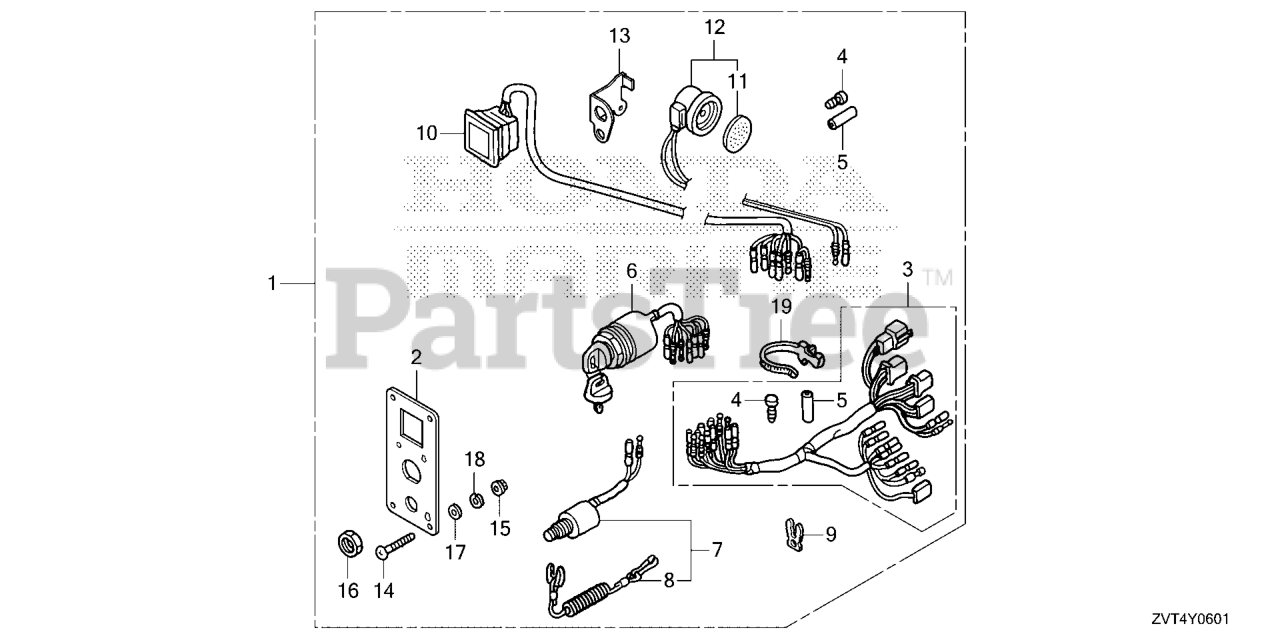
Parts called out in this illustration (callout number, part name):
1	PANEL KIT, SWITCH (4-LED)
2	PANEL, CONTROL
3	HARNESS ASSY., SWITCH PANEL
4	PLUG, CONNECTOR (INNER) (TROLLING CONTROL)
5	PLUG, CONNECTOR (OUTER) (ENGINE NO.)
6	SWITCH ASSY., COMBINATION (SINGLE) (DUAL)
7	SWITCH ASSY., EMERGENCY STOP
8	WIRE, EMERGENCY (SINGLE) (DUAL)
9	CLIP, EMERGENCY LOCK
10	LAMP ASSY., INDICATION (4-LED)
11	PLATE, TURN SIGNAL BUZZER DUAL QTY = (2) (SINGLE)
12	BUZZER, WARNING DUAL QTY = (2) (SINGLE)
13	BRACKET, BUZZER
14	SCREW, PAN (5X40) DUAL QTY = (8) (SINGLE)
15	NUT, FLANGE (5MM)
16	NUT, HEX. (16MM) DUAL QTY = (2) (SINGLE)
17	WASHER, PLAIN (5MM)
18	WASHER, SPG (5MM)
19	BAND, WIRE HARNESS (150MM) (NATURAL) DUAL QTY = (2) (SINGLE)
